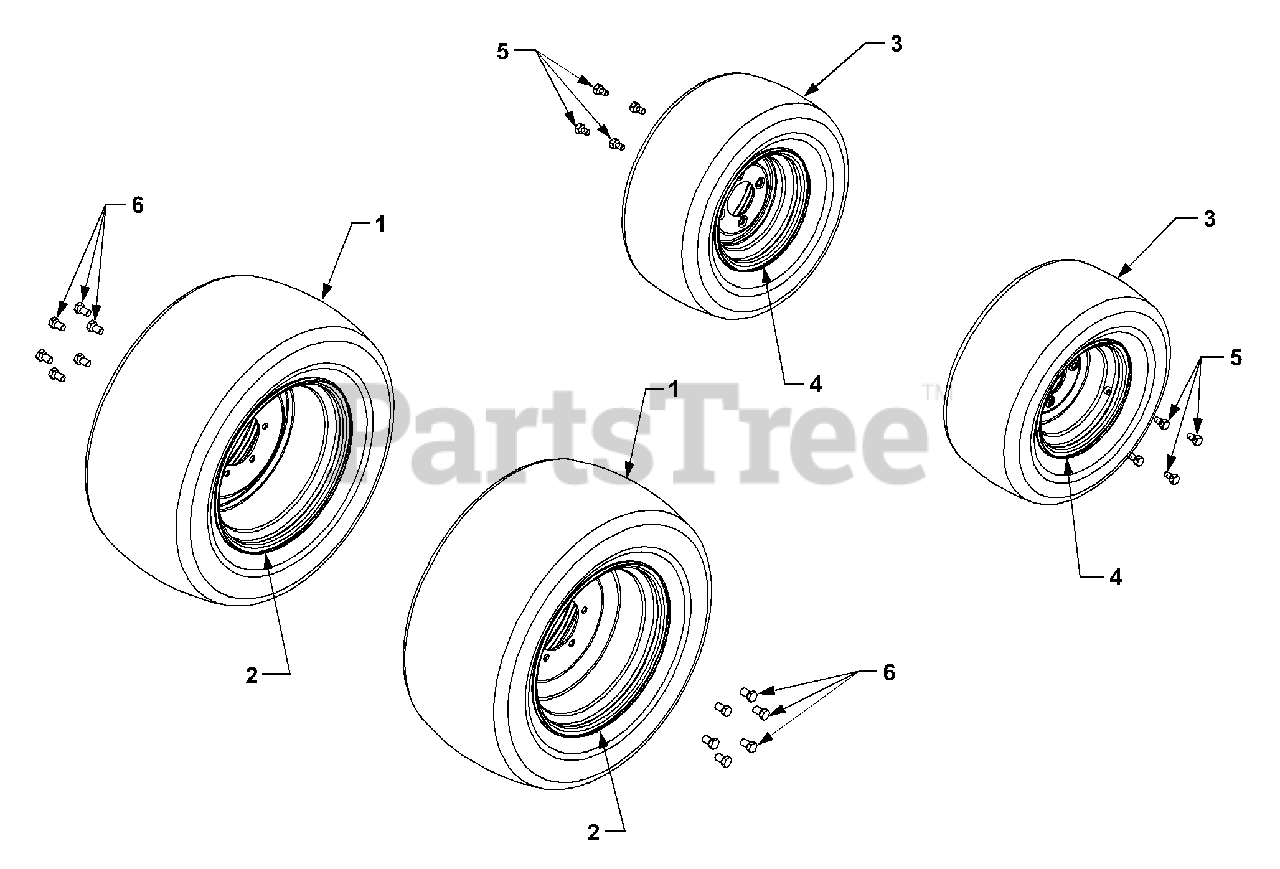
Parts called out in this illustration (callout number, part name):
1	Tire, Turf, 27 x 12.0 x 15
2	Rim Assembly
3	Tire, Tuft, 20 x 9 x 8
5	Screw, Lug, M12
6	Bolt, Lug, M14 x 1.5 x 20
